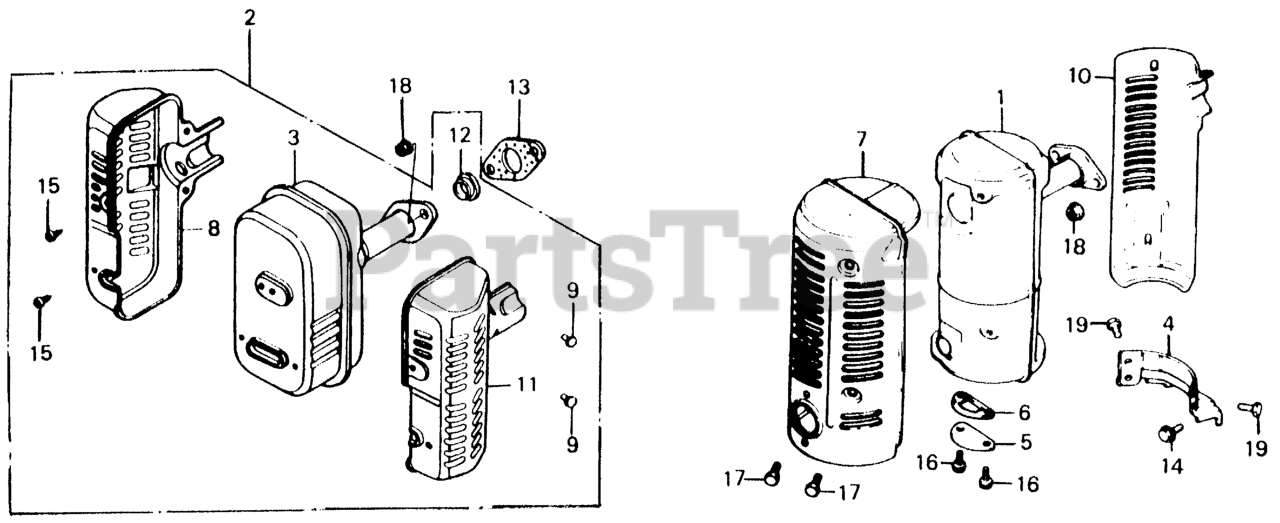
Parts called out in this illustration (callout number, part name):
1	MUFFLER ASSY.
2	MUFFLER ASSY. (NOT AVAILABLE)
3	MUFFLER ASSY.
4	STAY, MUFFLER
5	LID, MUFFLER
6	GASKET, MUFFLER LID
7	PROTECTOR A, MUFFLER
8	PROTECTOR, L. MUFFLER
9	RIVET (4X5) Use up to Engine SN 1012894.
10	PROTECTOR B, MUFFLER
11	PROTECTOR, R. MUFFLER
12	SHIM, GASKET
13	GASKET, MUFFLER
14	BOLT, FLANGE (8X16)
15	SCREW, TAPPING (4X8)
16	BOLT, HEX. (6X12)
17	BOLT, HEX. (6X6)
18	NUT, FLANGE (8MM)
19	BOLT, FLANGE (6X10)
